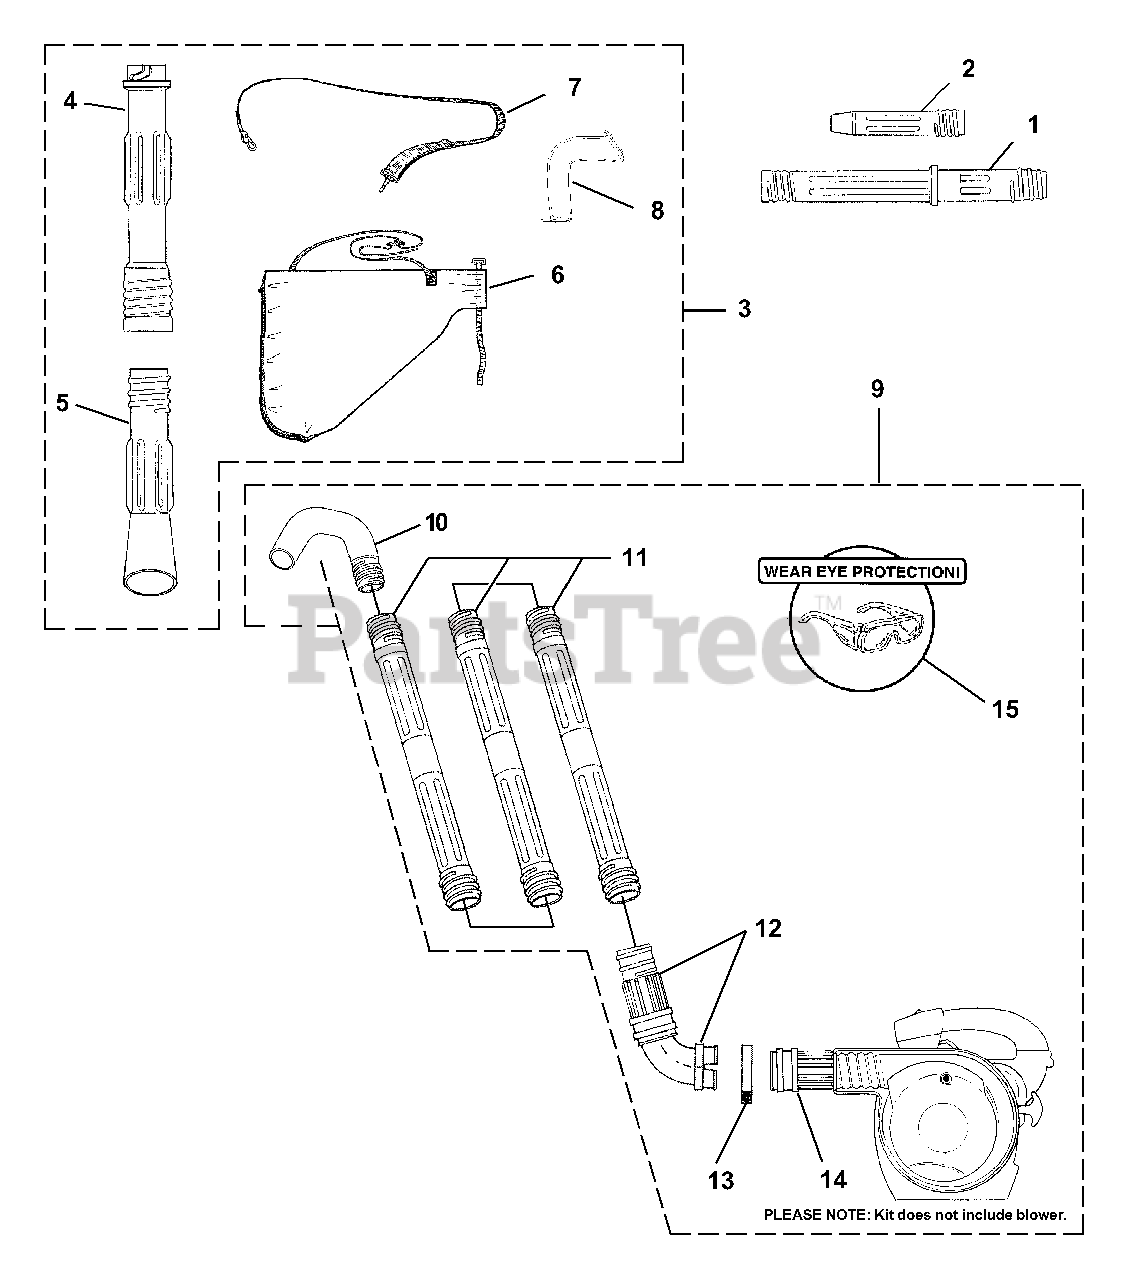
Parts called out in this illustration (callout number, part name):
1	Tube, Blower
2	Nozzle, Blower
3	Vacuum Kit
4	Vac Tube, Upper
5	Vac Tube, Lower
6	Bag
7	Shoulder Strap
8	Air Deflector
9	Gutter Maintenance Kit
10	Full Elbow
11	Straight Tube
12	Upper Elbow & Swivel Adapter
13	Large Clamp
14	Adapter
15	Safety Glasses - Clear
